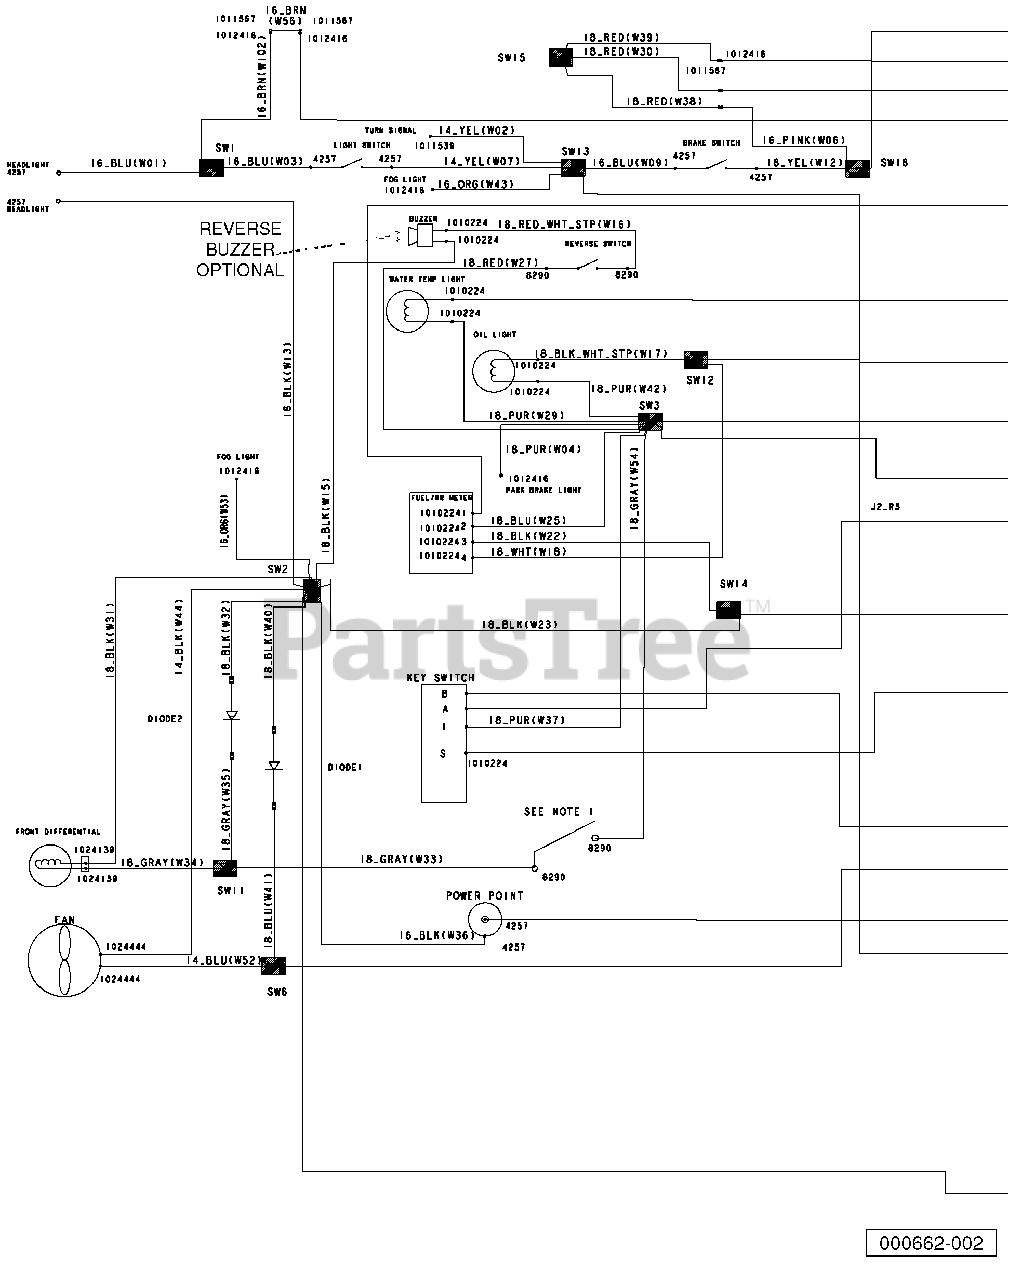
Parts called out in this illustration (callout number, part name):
1	Diode, General Purpose, 6.0a
2	Harness, AWD, Kawasaki
3	Asm, Switch, Limit, Awd
